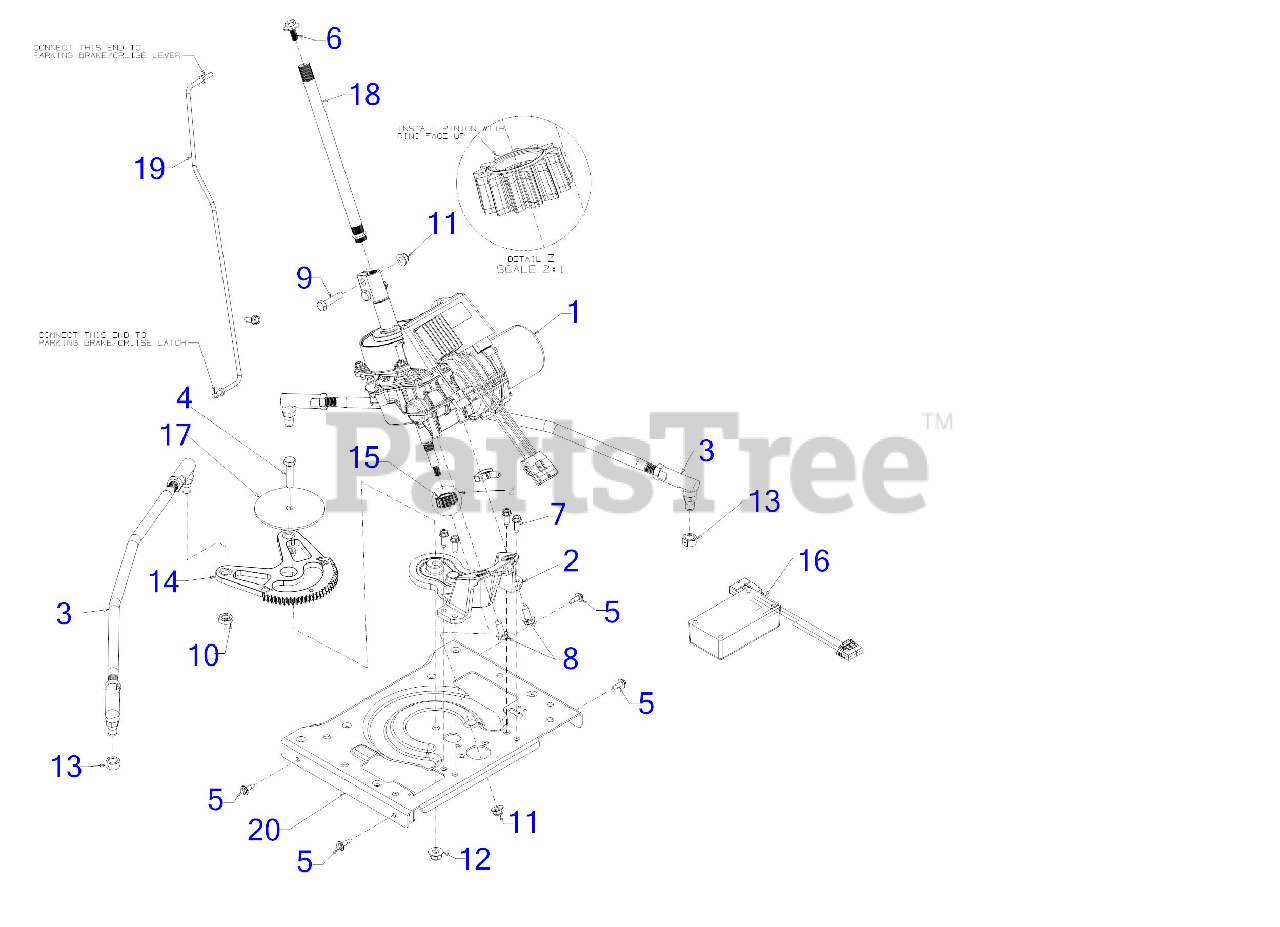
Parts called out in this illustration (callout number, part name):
1	POWER STEERING TRANSMISSION ASSEMBLY
2	STEERING MOUNTING HOUSING ASSEMBLY
3	STEERING TIE ROD
4	SCREW 3/8-16 x 1.50
5	SCREW M6-1 x .625
6	SCREW 5/16-24 x .85 GR5
7	SCREW 1/4-20 x .750
8	SCREW 5/16-18 x .750
9	BOLT 5/16-18X1.375 GR5
10	JAM NUT 7/16-20
11	FLANGE LOCK NUT 5/16-18
13	HEX LOCK NUT 7/16-20
14	STEERING SEGMENT GEAR
15	STEERING PINION GEAR 13T
16	VOLT PROTECTOR HARNESS EPS PURPLE
17	FLAT WASHER .385 x 3.75 x .120 THK
18	STEERING SHAFT 10.28
19	CRUISE/BRAKE ROD
